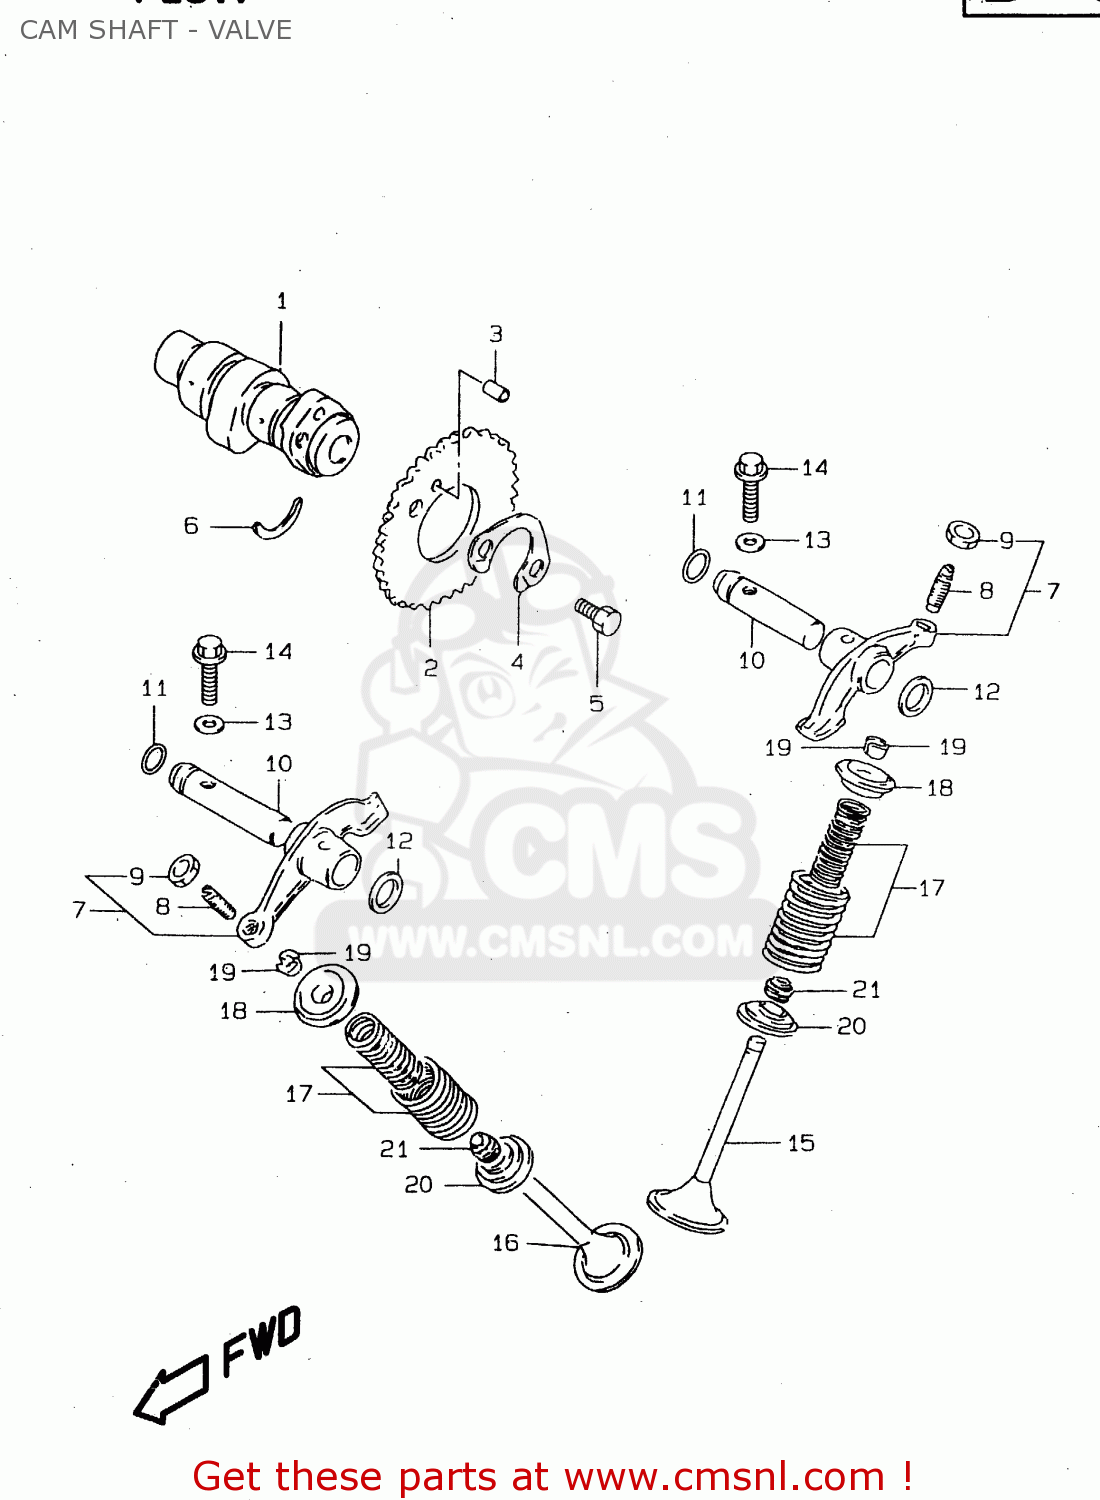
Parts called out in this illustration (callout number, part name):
1	CAMSHAFT
2	SPROCKET,CAMSHAFT
3	PIN(5X8)
4	WASHER,SPROCKET
5	BOLT(6X10.5)
6	C RING
7	ARM ASSY,VALVE ROCKER
8	SCREW,TAPPET ADJUSTING
9	NUT,ADJUSTING SCREW
10	SHAFT,VALVE ROCKET
11	O RING(D:1.9,ID:8.6)
12	WASHER
13	GASKET(5.8X13X1.2) (NAS)
14	BOLT
15	VALVE,INTAKE
16	VALVE,EXHAUST
17	SPRING SET,VALVE
18	RETAINER,VALVE SPRING
19	COTTER,VALVE
20	SEAT,VALVE SPRING
21	SEAL,OIL(5.5X11X8.2)
